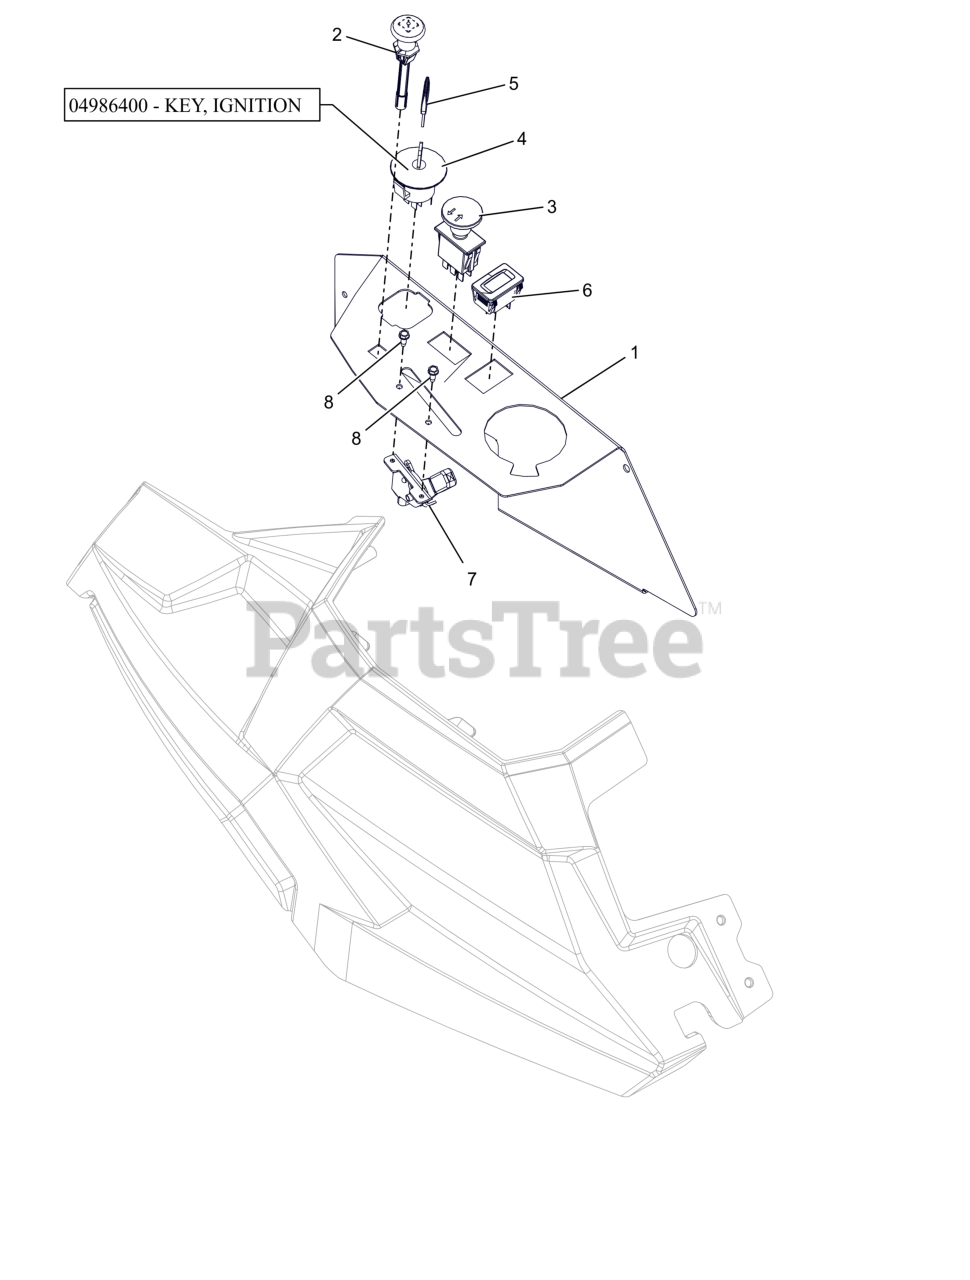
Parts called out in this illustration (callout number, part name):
1	PANEL, CONTROL (RED)
2	CABLE - CHOKE, SNAP-IN
3	SWITCH, CLUTCH (YELLOW)
4	KEYSWITCH-IGNITION 4 POS
5	KEY, IGNITION
6	HOUR METER
7	CABLE - THROTTLE CONTROL
8	SCR,TAP #10-24X.50 HWH TR ZCC
